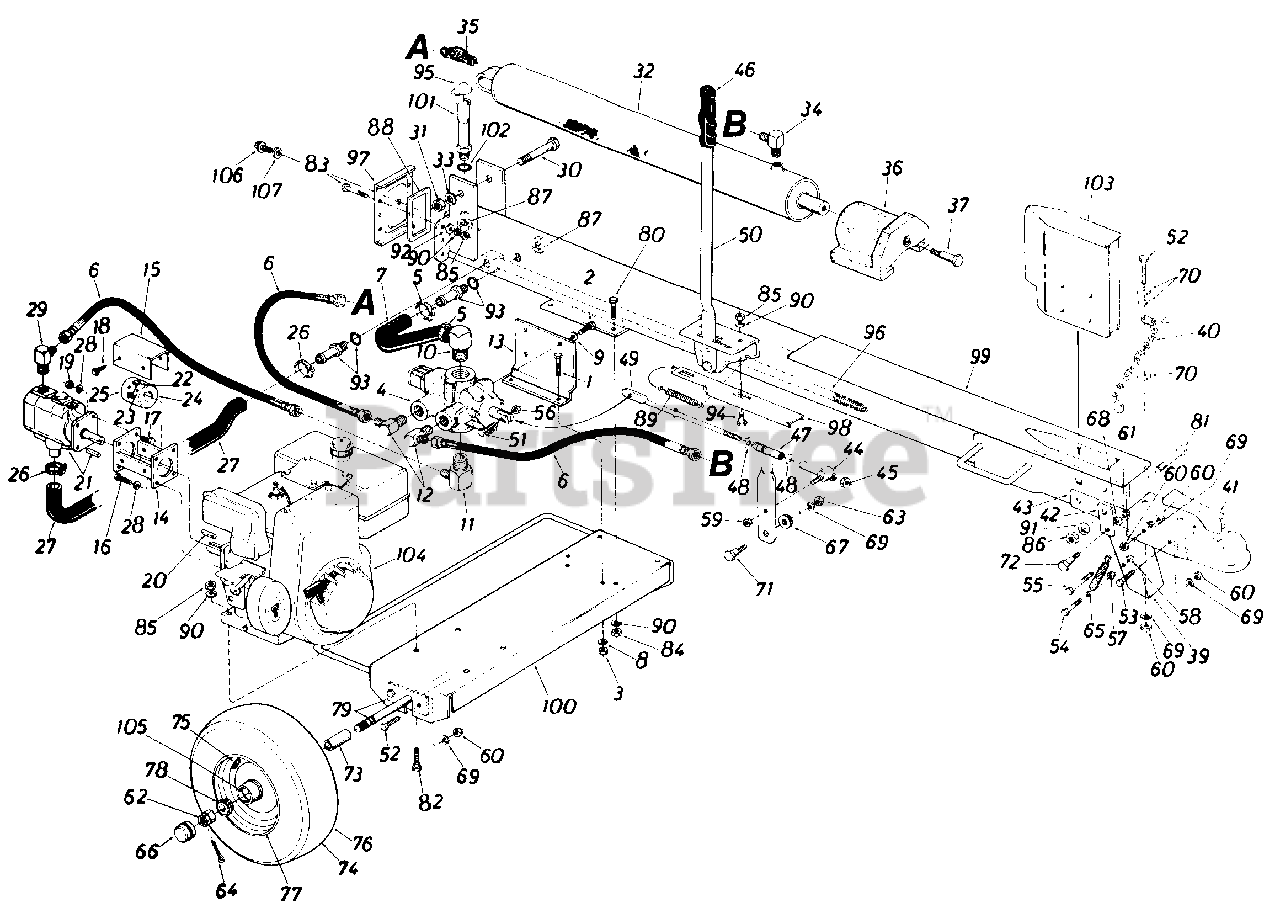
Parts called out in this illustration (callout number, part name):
1	Hex Bolt 5/16-18 x .75" Lg.*
2	Hex Bolt 3/8-16 x .60" Lg.*
3	Hex Nut 5/16-18 Thd.*
4	Control Valve 400
5	Hose Clamp 5/8"
6	High Pressure Hose Ass'y. .38" I.D.
7	Return Hose-Valve to Tank 3/4" I.D.
8	L.-Wash.5/16" I.D.*
9	L.-Wash. 3/8" I.D.*
10	Return Elbow
11	90ø Solid Male Adapter
12	90ø Solid Male Adapter
13	Valve Mtg. Plate
14	Coupling Support Brk't. Ass'y.
15	Coupling Shield
16	Hex Bolt 5/16-24 x 1.00" Lg.*
17	Hex Bolt 5/16-24 x .75" Lg.*
18	Hex Wash. Hd. Tap Scr. 1/4-20 x .38" Lg.
19	Hex Nut 5/16-24 Thd.*
20	Sq. Key 1/4" x 1/4" x 2.25" Lg.
21	Pump with Woodruff Key
22	Spider L-0-90
23	Set Scr. 1/4-20 x .25" Cup
24	Coupling Half 1.00" I.D.
25	Coupling Half .50" I.D.
26	Hose Clamp 5/8"
27	Suction Hose 1.0" Dia.
28	L.-Wash. 5/16" I.D.*
29	90ø Solid Male Adapter
30	Hex Bolt 3/4" x 4.0" Lg.
31	Hex Nut 3/4" Thd.*
32	Hydraulic Cylinder 3-1/2" Dia.
33	Hydraulic Cylinder 4" Dia.
34	90ø Male Adapter 3/4-16 MJ 3/8-18 NPT
35	45ø Male Adapter 3/4-16 MJ-3/8-1 8 NP
36	Pusher Plate
37	Shoulder Bolt .62" Dia. x 4.75" Lg. (1/2-13 Thd.)
39	Flip Stand Bracket
40	Chain-Tow Hitch
41	Tow Hitch Ass'y. Comp.
42	Stand Pivot Bracket
43	Tow Hitch Brk't. 2 x 3/16 x 10.25" Lg.
44	Ferrule Ass'y.
45	Hex Cent. L.-Nut 3/8-24 Thd.
46	Grip-Black Vinyl
47	Compression Spring
48	Special Washer .378 x 1.00" x .125 Thd.*
49	Engagement Rod 3/8" Dia. x 9.0" Lg.
50	Engagement Handle
51	Hex Bolt 1/4-20 x 1.75" Lg.*
52	Hex Bolt 3/8-24 x 1.00" Lg.*
53	Hex Bolt 3/8-24 x .75" Lg.*
54	Hex Bolt 1/4-28 x 1.00" Lg.*
55	Hex Bolt 3/8-24 x 1.75" Lg. . Grade 5
56	Hex Patch L.-Nut 1/4-20 Thd .
57	Hex Cent. L.-Nut 1/4-28 Thd.
58	Hex Nut 1/4-28 Thd.
59	Hex Cent L.-Nut 5/16-18 Thd.
60	Hex Nut 3/8-24 Thd.*
61	Hex Nut 5/16-19 Thd.*
62	Hex Castle Nut 3/4-1 6 Thd.
63	Hex Nut 3/8-16 Thd.*
64	Cotter Pin 5/32" Dia. x 1.25" Lg.*
65	Extension Spring .50" O.D. x 3.97." Lg.
66	Hub Cap
67	Rubber Washer
68	L.-Wash. 5/16" I .D.*
69	L.-Wash. 3/8" I.D.*
70	Fl.-Wash. .375" I.D. x .870" O.D. x .090
71	Shoulder Bolt .498" Dia. x x .340" Lg.
72	Shoulder Bolt .437" Dia. x .268" Lg.
73	Spacer.75" I.D. x 1.12" O.D. x 1.56" Lg.
75	Air Valve-Tubeless
76	Tire Only 16.0 x 4.0-2 Ply
78	Roller Rearing 3/4" I.D.
79	Axle Ass'y. .75" Dia. x 35.25" Lg.
80	Hex Bolt 5/16-24 x 1.00 Lg.*
81	Hex Bolt 5/8-18 x 3.50" Lg.*
82	Hex Bolt 5/16-24 x 1.75 Lg.*
83	Hex Bolt 5/16-18 x 1.50" Lg.*
84	Hex Nut 5/16-24 Thd.*
85	Hex Nut 5/16-18 Thd.*
86	Hex Nut 5/8-18 Thd.*
87	Hex Nut 11/16-12Thd
88	Gasket 2.62 x 5.12
89	Extension Spring .50" O.D. x 4. 25" Lg.
90	L.-Wash. 5/16" I.D.*
91	L.-Wash. 5/8" I.D.*
92	Fl.-Wash. 34" I.D. x .68" O.D. x .062 Thk.
93	Adapter 1.0" Tube 1 1/16-12 "O"-Ring
94	Shoulder Bolt .437" Dia. x .180" Lg.
95	Oil Fill Cap
96	Strainer Tube Ass'y.
97	End Plate
98	Engagement Brk't. 1.39 x 11.75" Lg.
99	Complete Oil Tank Ass'y.
100	Engine Frame Ass'y.
101	Filler Tube Ass'y.
102	"O"-Ring 92" I.D. x 1.16" O.D. x .116 Dia.
103	Wedge Ass'y.
104	5 H.P. Engine
105	Bearing Seal
106	Hex Hd. Tap Scr. 5/16"
107	Gasket
